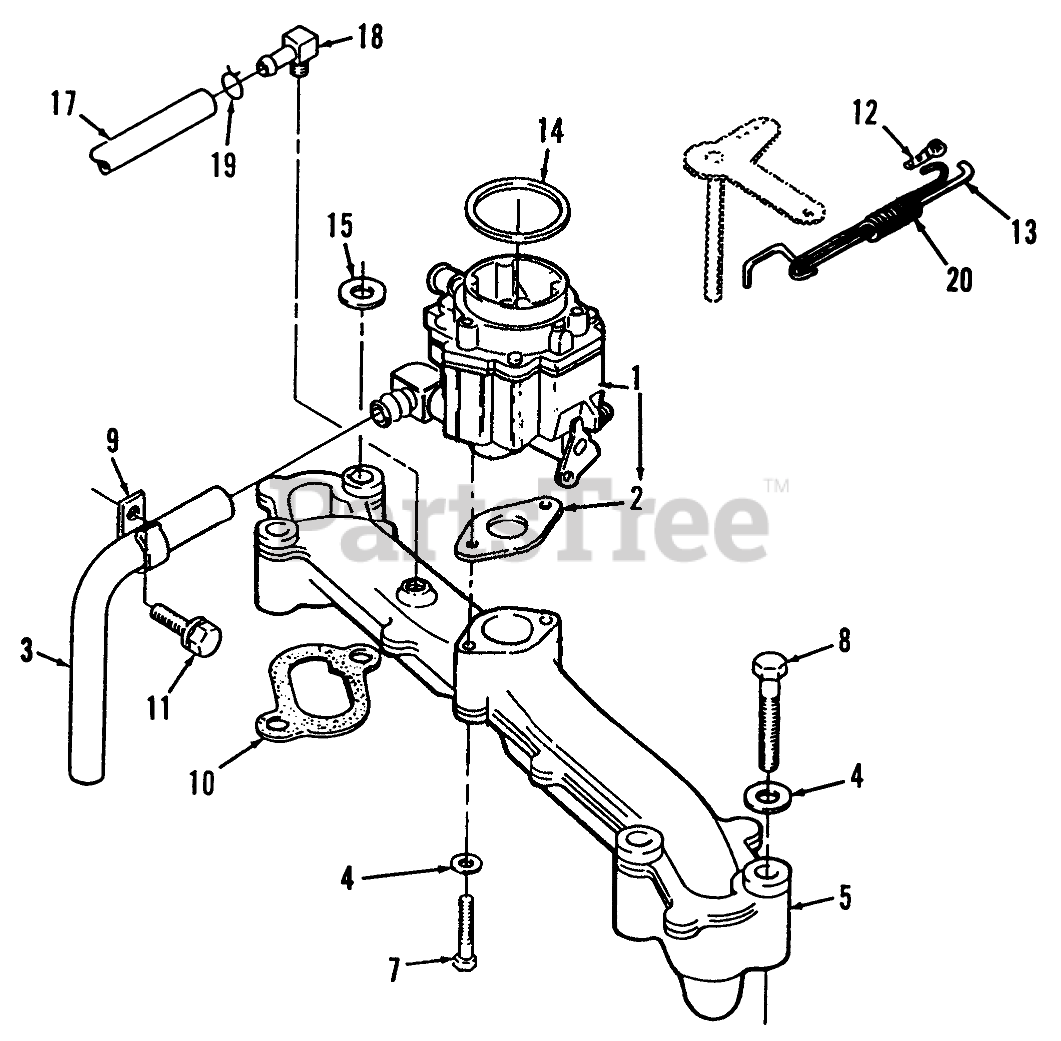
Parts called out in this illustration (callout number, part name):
1	Carburetor, Complete (Includes Mounting Gasket, Elbow and O-Ring)(See Separate Page for Components)
2	Gasket
4	WASHER-FLAT
5	MANIFOLD
6	WASHER-FLAT
7	Bolt
9	Clip
10	GASKET
11	SCREW-HWH
12	Retaining Clip
13	Governor Control Rod
15	FLAT WASHER
16	Hose, Fuel
17	HOSE-RUBBER, BREATHER
18	FITTING-BARB
19	CLAMP-HOSE
20	Spring-Governor Rod
